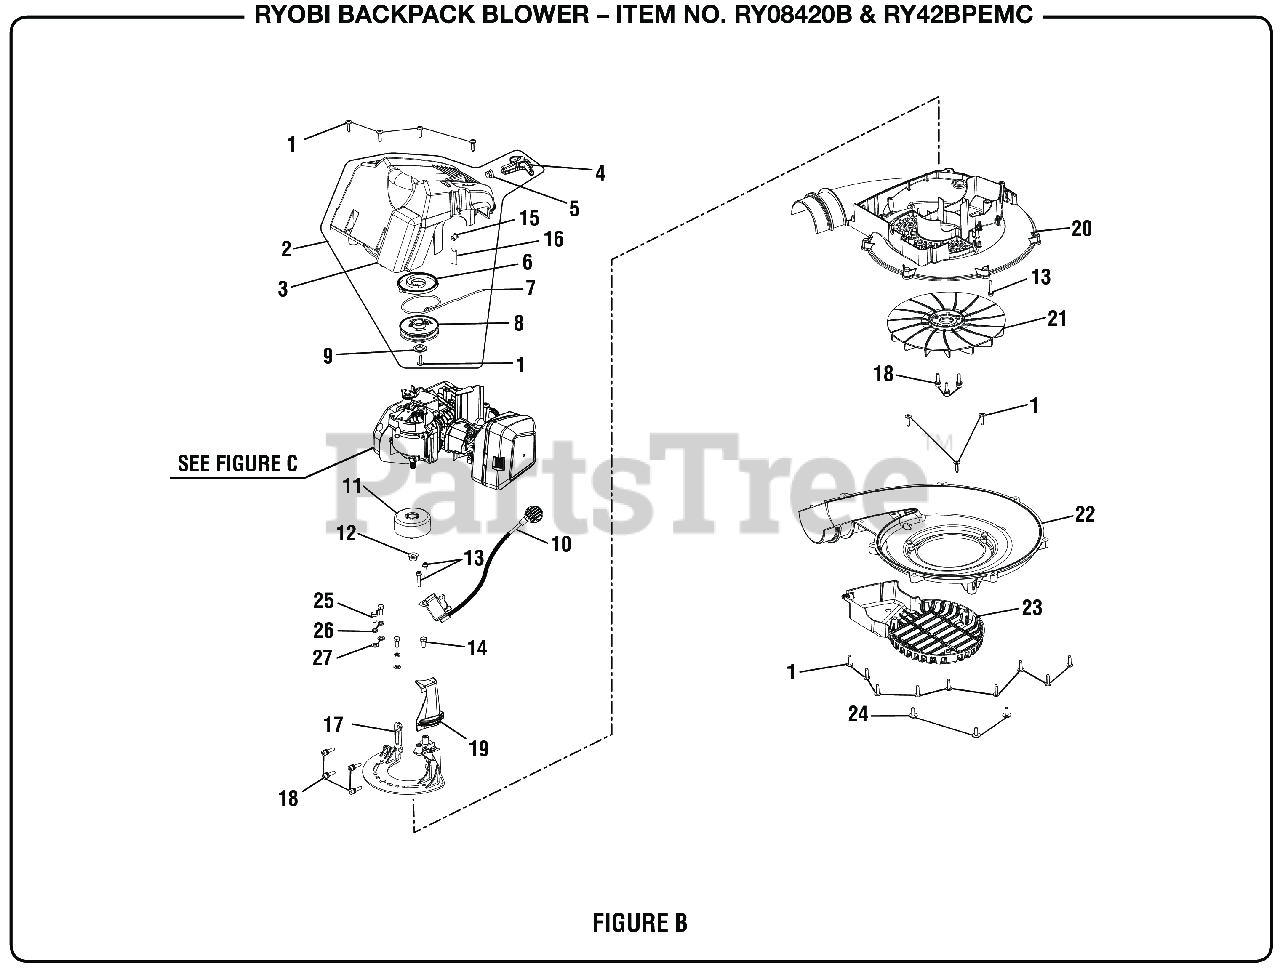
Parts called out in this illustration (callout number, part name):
1	Screw (10-14 x 19 mm, T25 Torx Truss Pan Hd. T.F.)
2	Engine Cover w/Starter Assembly
3	Motor Cover
4	Starter Grip
6	Spring & Container Assembly
7	STARTER ROPE 42 (PKG)
8	Starter Pulley
9	Starter Cap
10	Ignition Module
12	Lock Nut (M8 x 1.25 in., Left Hand Threads)
13	Screw w/Washer (M5 x 25.4 mm, T25 Pan Hd. T.F.)
14	Screw (M6 x 16 mm)
16	Eyelet Support
17	Engine Mount
18	Screw w/Washers (M5 x 20 mm, Hex Soc. Hd.)
19	Cable Guide/Baffle Plate
20	Inner Volute
22	Outer Volute
23	Outer Volute Cover
24	Screw (10-14 x 16 mm)
25	Screw (M6 x 14 mm, Hex Soc. Hd.)
26	Spring Washer (ID6.4 x 1.6t)
27	Washer (OD12.9 x ID6.6 x 1.2t)
